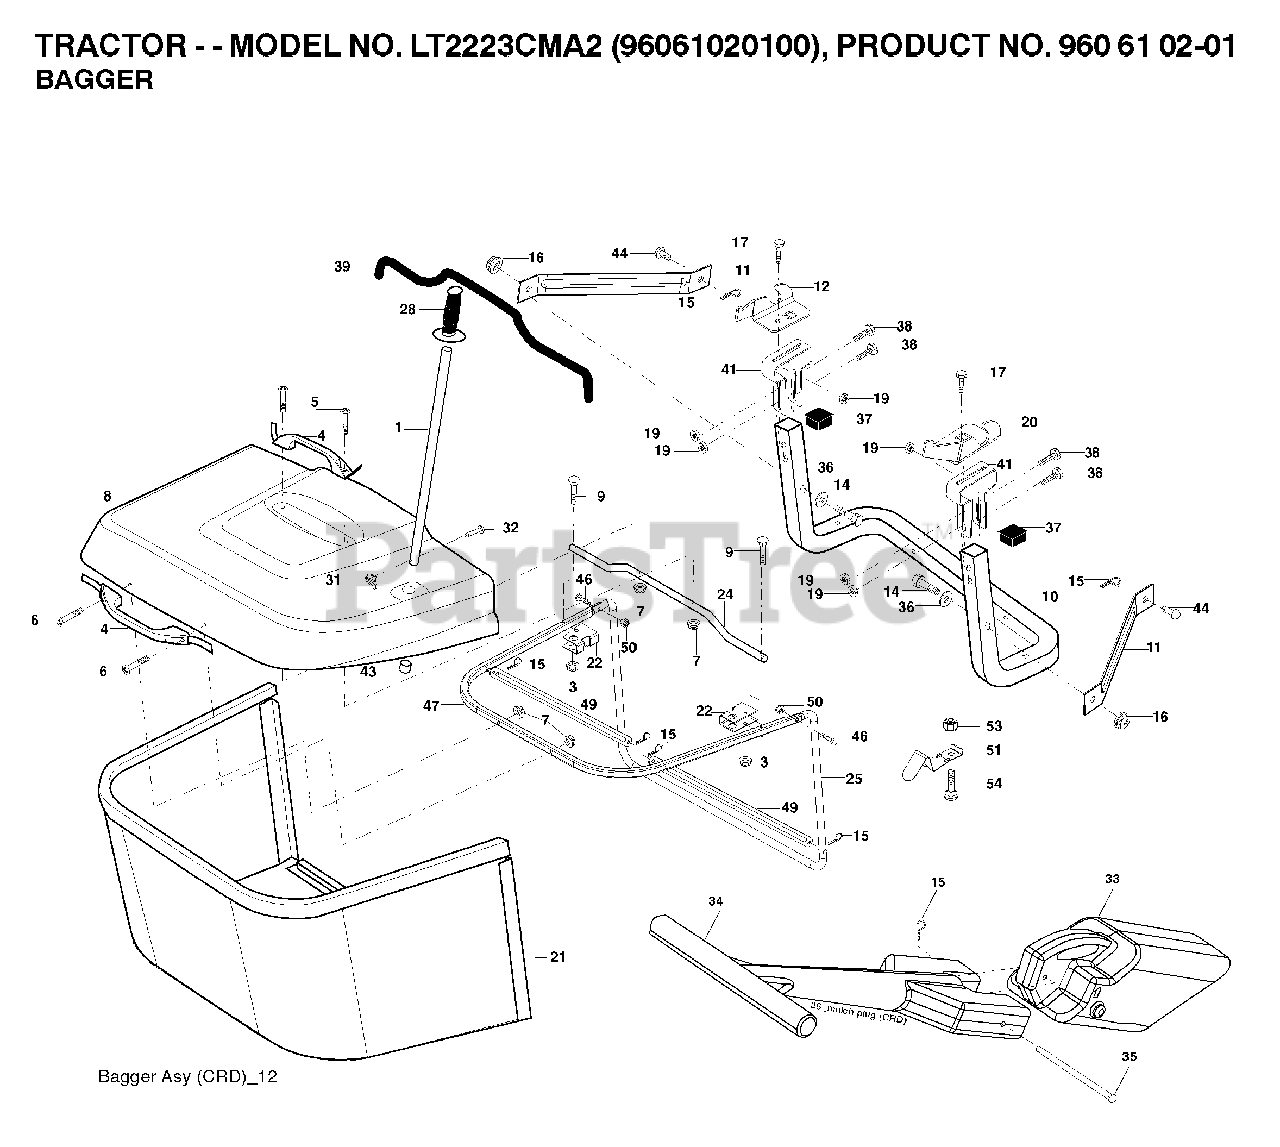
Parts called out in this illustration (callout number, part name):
1	TUBE HANDLE
3	NUT T
5	SCREW.PAN.HEAD
11	BRACKET
14	BOLT-HEX EAK
15	RETAINER-SPRNG RB
16	NUT LOCK FLG 3/8-16 UNC
17	BOLT
19	NUT LOCK HEX FLANGE 5/16-18
20	BRKT.PIVOT.RH.CRD
21	BAGGER.ASM.CRD.2007
22	BRACKET
24	TUBE
28	GRIP.HANDLE.BLACK
31	RETAINER CLIP
32	RIVET,DRILLED
33	MULCH PLUG, CTH150
35	PIN
38	BOLT.5/16-18X2.5
41	BRKT, BAGGER
43	PLUG, TUBING END
46	BOLT.CARRIAGE.5/16-18
50	NUT.71038.31-18.HEX.NYLOCK
53	NUT
54	BOLT
